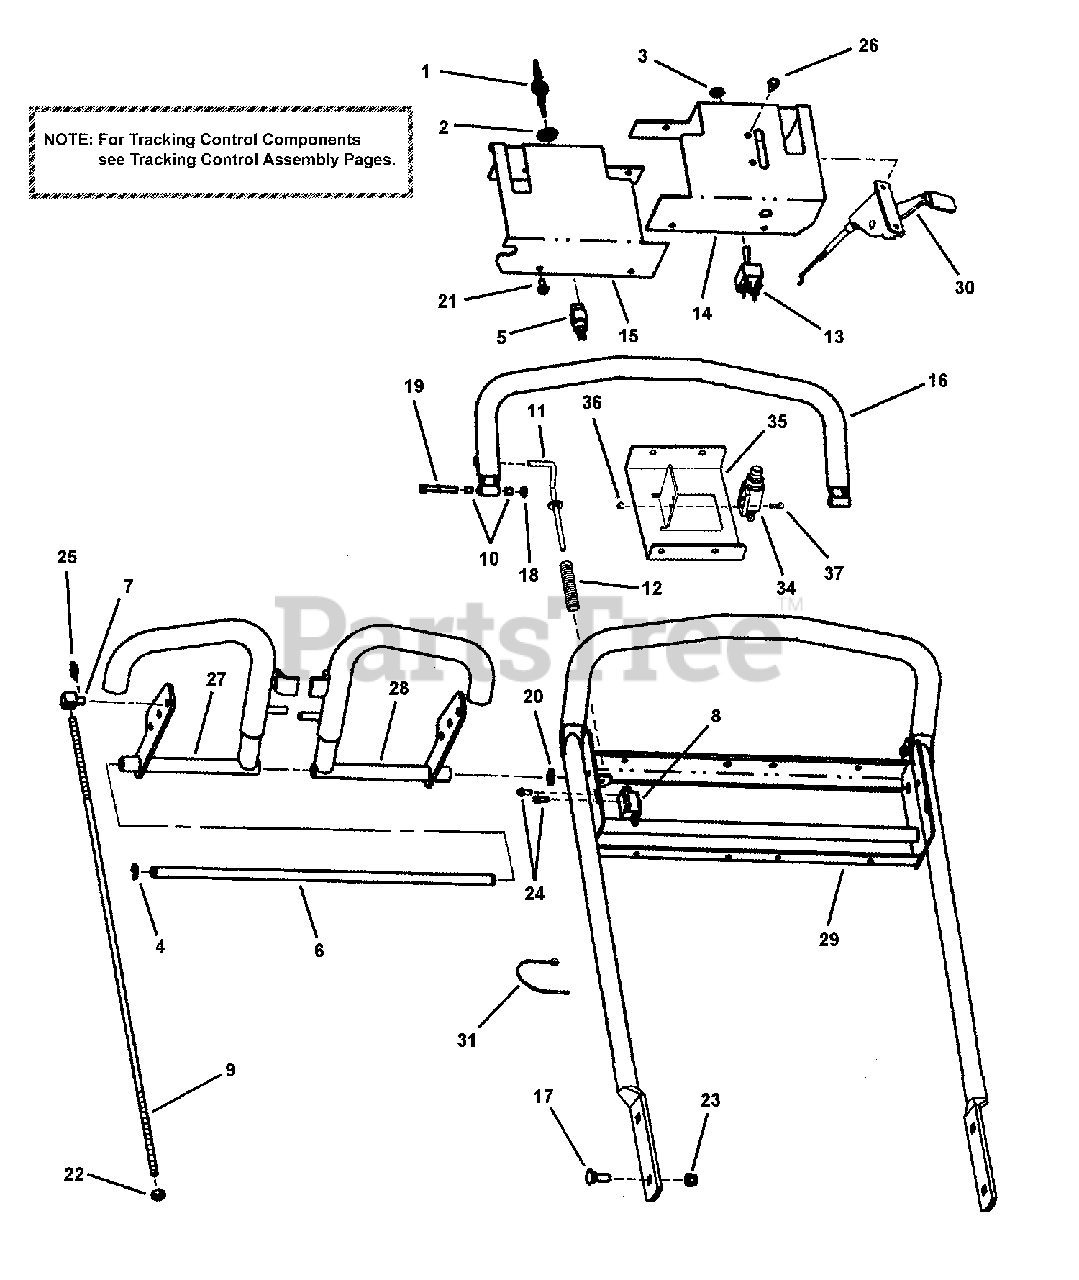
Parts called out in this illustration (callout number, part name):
1	IGNITION KEY, Pair
2	NUT, 5/8-32 Hex (Ignition Switch)
3	NUT, 1/2-27 Hex (Special)
4	RETAINING RING
5	SWITCH, Ignition, 2-Pole, Recoil Start
5	SWITCH, Ignition
6	ROD, Pivot, 1/2" Dia. x 18.542 w/2 retaining Ring Grooves
7	SWIVEL
8	SWITCH, OPC, Single Pole (NC)
8	SWITCH, OPC, (NO/NC)
9	CONTROL ROD (Traction)
10	BEARING, Nyliner
11	ROD, Operator Presence Control
12	SPRING, OPC- Loop Handle
13	SWITCH, Toggle
14	PANEL, Left
15	PANEL, Right
16	BAIL, Operator Presence Control (Weldment)
17	BOLT, 5/16-18 x 1" Short Neck Carriage, GR 5
18	NUT, 1/4-20 Hex Jam
19	BOLT, 1/4-20 x 1-3/4" Hex Head Cap, GR 5
20	BUSHING, 1/2" Machine
21	SCREW, 1/4-20 x 1/2" Hex Washer Self-Tap
22	NUT, 5/16-24 Hex, GR 5
23	NUT, 3/8-16 HEX NYLON LOCK
24	SCREW, #12-14 x 1/2" Hex Flange Self-Tap
25	COTTER PIN, 1/2" Self-Locking
26	SCREW, 1/4-20 x 3/4" Hex Washer Self-Tap
27	WELDMENT, Traction Lever, RH
28	WELDMENT, Traction Lever, LH
29	HANDLE, Loop (Weldment)
30	THROTTLE CONTROL, 40.50/1.46
30	THROTTLE CONTROL, 51.50/0.90
30	THROTTLE CONTROL, 48.50/0.90
31	CABLE TIE, 7"
34	SWITCH, Interlock, Sealed (NC)
34	SWITCH, Interlock, Sealed (NO/NC)
35	BRACKET, Interlock Switch
36	NUT, #10-32 Hex Nyloc
37	SCREW, #10-32 x 5/8" Hex Machine
